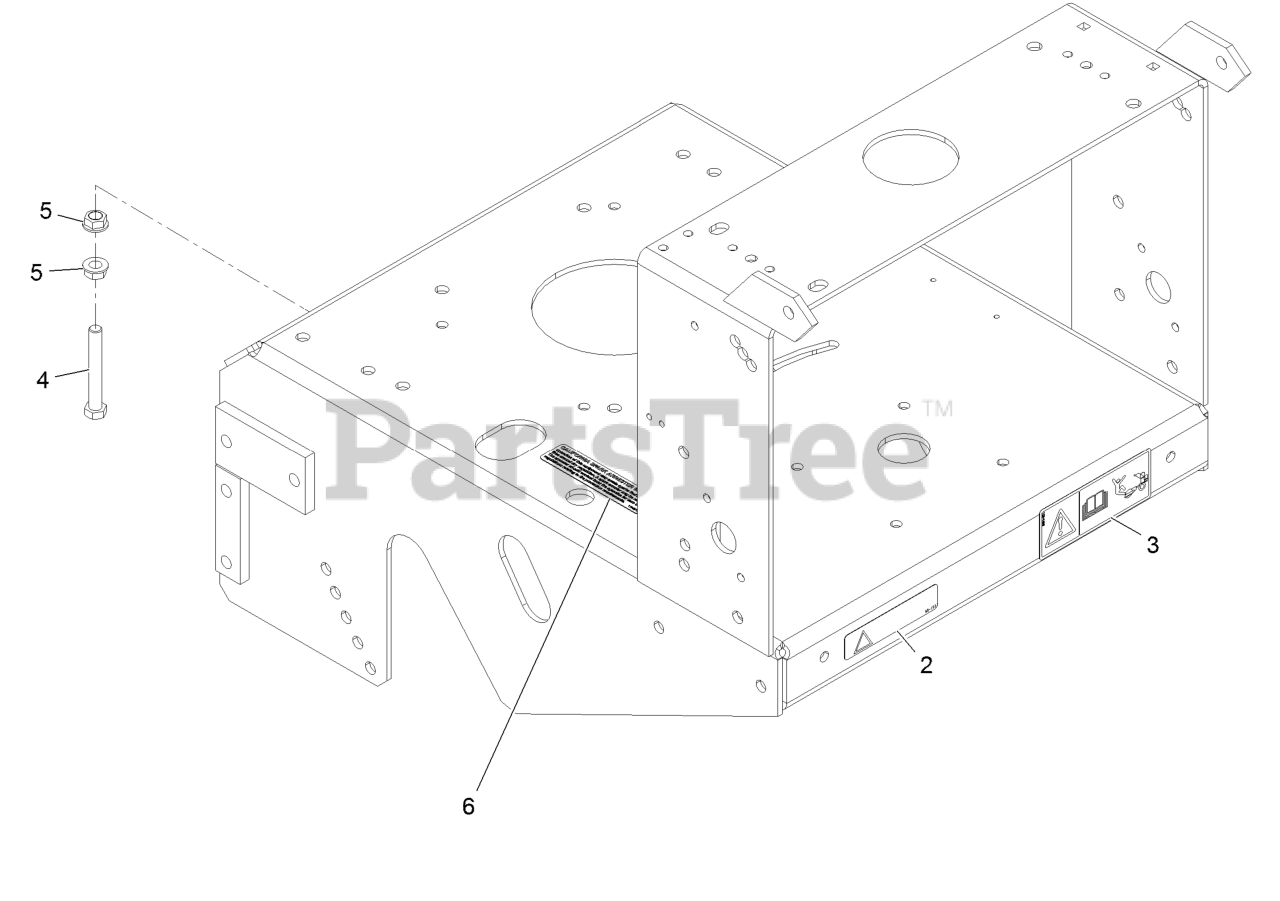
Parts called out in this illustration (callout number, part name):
2	Decal-Warning
3	Decal-Warning, Sulky
4	Screw-HH
5	Nut-HHF, Whiz
6	Decal-Arrester, Spark
